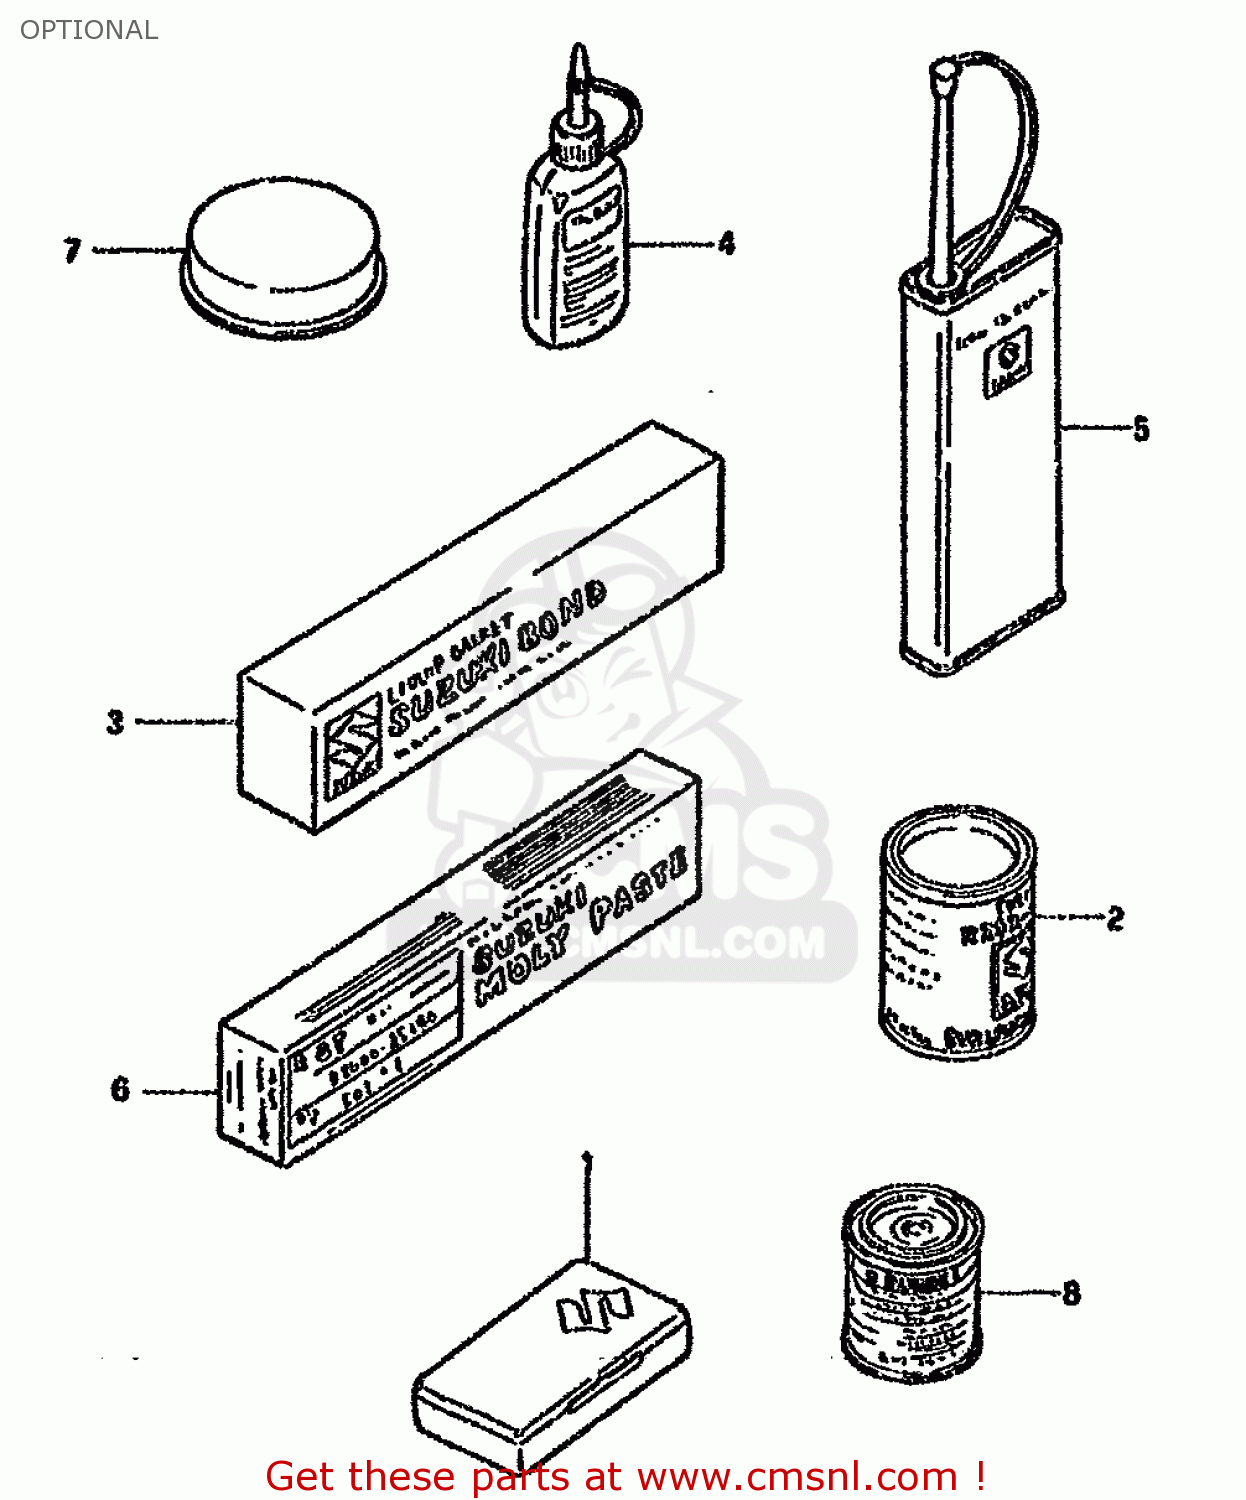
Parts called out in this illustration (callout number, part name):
1	TUBE REPARING TOOL
2	GREASE(C)EP2 LITHIUM 150G
3	LIQUID GSKT NO.1215 250G
4	THREAD LOCK NO.1342
5	THREAD LOCK NO.1401 CLEAR 200G
6	SUZUKI MOLY PASTE
7	GREASE,PBC FOR BRK PAD 20G
8	PAINT,BLACK
